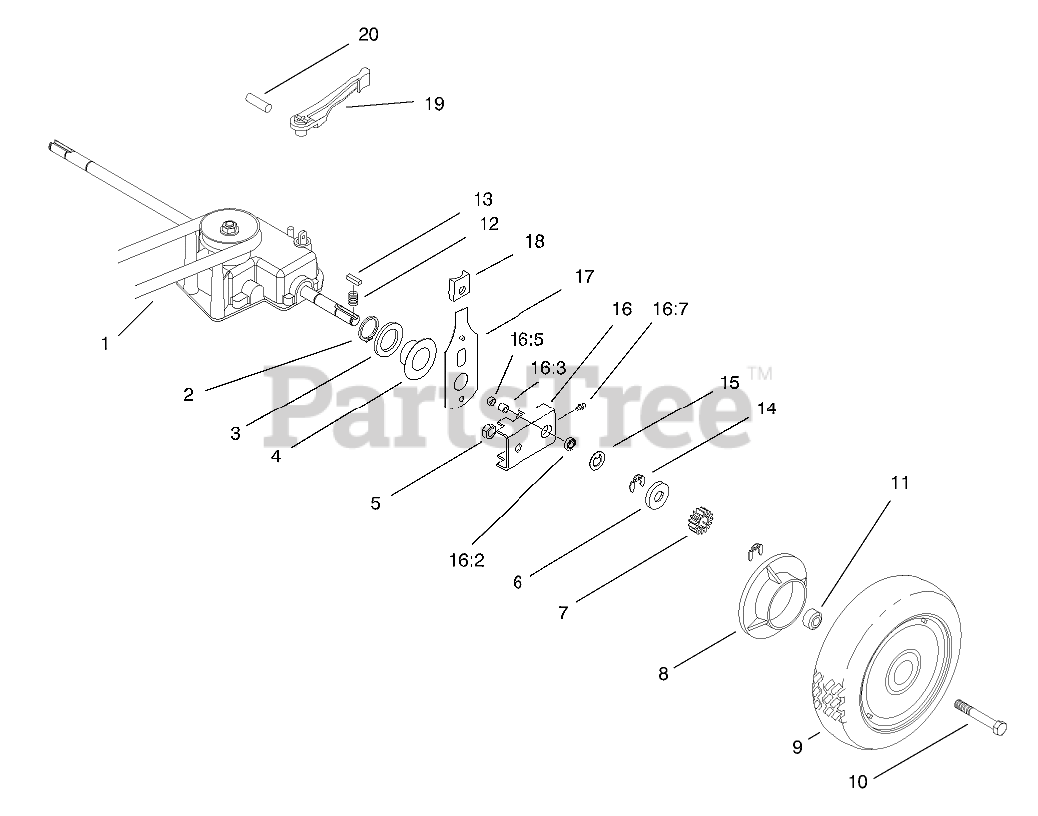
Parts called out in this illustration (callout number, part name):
1	V-BELT
2	RING-RETAINING
3	WASHER
4	CAP-END
5	NUT-LOCK, CONE
6	WASHER-THRUST, OUTER
7	GEAR-PINION
8	COVER-WHEEL
9	WHEEL AND TIRE ASM
10	SCREW-HH
11	SPACER-COVER, WHEEL
12	SPRING-COMPRESSION
14	RING-RETAINING
15	WASHER-THRUST, OUTER
16	PIVOT ARM ASM
16:2	BEARING-WHEEL
16:3	BEARING-ROLLER
16:5	SEAL-OIL
17	REAR SPRING ARM ASM
18	KNOB-ARM
19	LEVER-SHIFT
20	PIN-COIL
